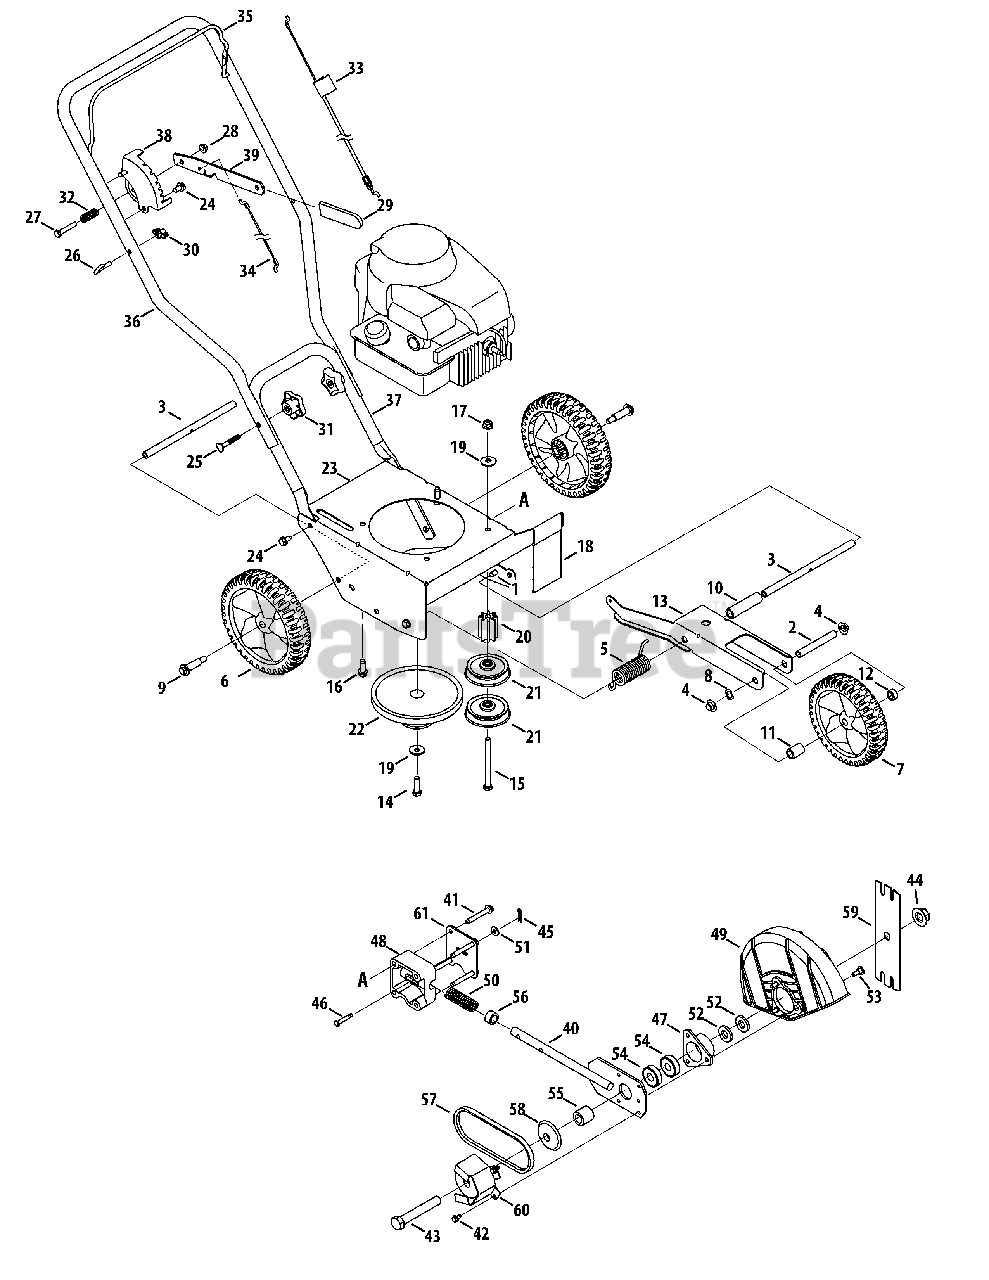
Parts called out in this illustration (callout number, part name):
1	Hex Head Screw 3/8-16
2	Axle .50 x 3.8
3	Axle .50 x 9.25
4	Push Cap 1/2" rod
5	Torsion Spring
6	Wheel 8x1.8
7	Wheel 7x1.8
8	Wave Washer
9	Shoulder Screw, .498 x 1.635
10	Spacer
11	Spacer, .525 x .775 x .93
12	Spacer, .525 x .775 x .3125
14	Screw 3/8-24
15	Screw 3/8-16
16	Screw, 3/8-16
17	Flange Lock Nut, 3/8-16
18	Debris Guard
19	Bell Washer, .396 x 1.140
20	Pulley Mount Spacer
21	Flat Idler Pulley, 2.5 OD
22	Combination Flywheel Pulley
23	Frame
24	Hex Screw, 5/16-12
25	Carriage Bolt, 5/16-18
26	Rope Guide (Eye Bolt)
27	Hex Screw, 5/16-18
28	Lock Flange Nut, 5/16-18
30	Wing Nut
31	Hand Knob
32	Compression Spring
33	Control Cable
34	Wheel Adjustment Cable
35	Blade Control
36	Upper Handle
37	Lower Handle
39	Depth Index Lever
40	Blade Plate Assembly
41	Hex Screw, 5/16-18
42	Self-tapping Screw, 1/4-20
43	Hex Screw, 5/8-18
44	Flange Nut, 5/8-18
45	Cotter Pin
46	Clevis Pin
47	Bearing Cup
48	Bearing Block
49	Blade Guard
50	Compression Spring
51	Flat Washer, .260 x.72
52	Flat Washer .635x1.24x.181
53	Shoulder Screw
54	Bearing, .625 ID x 1.57 OD
55	Spacer, .63 x 1.12 x 1.06
56	Spacer, .64 x.88 x .50
58	Sheave
59	Edger Blade
60	Belt Guard
61	Cover Plate
